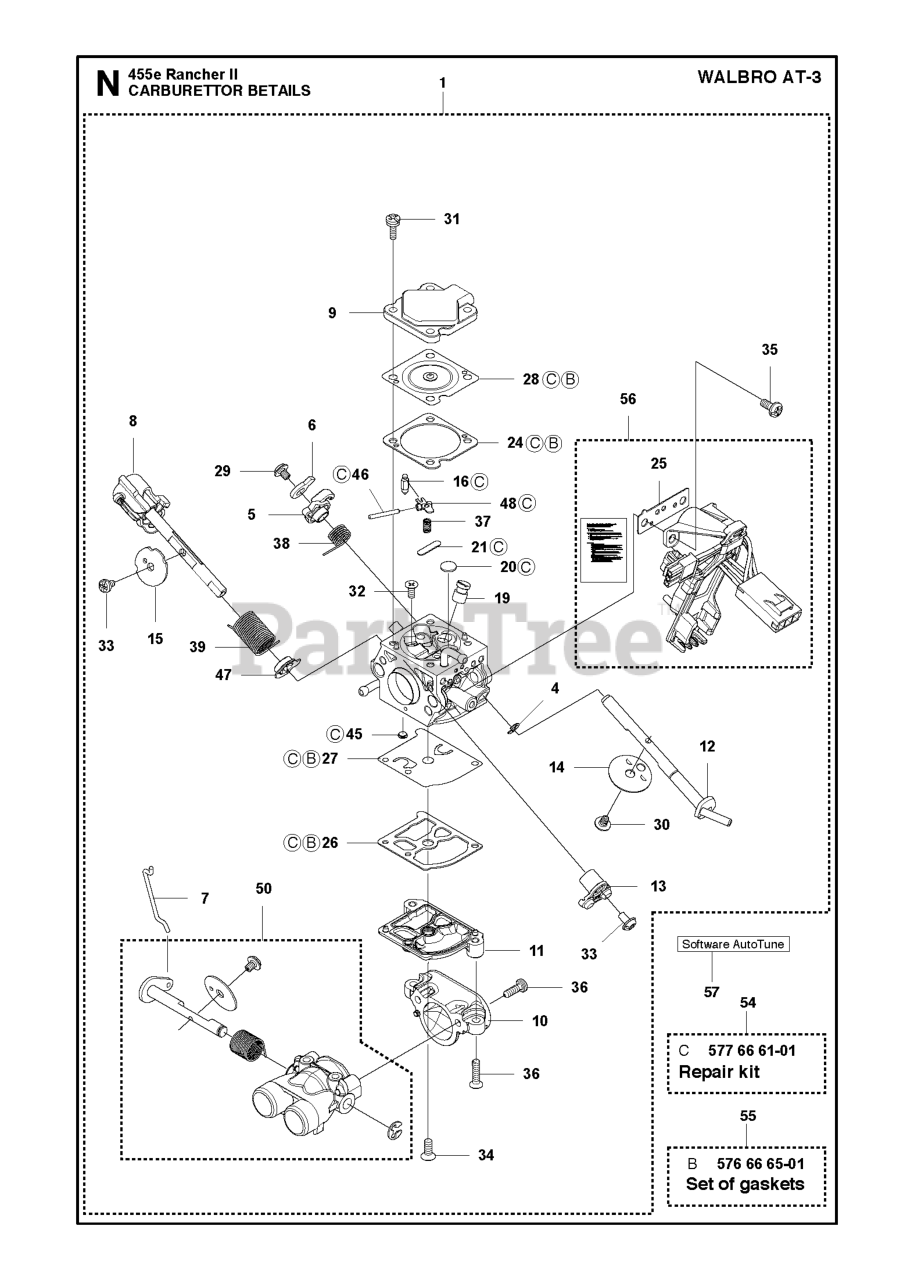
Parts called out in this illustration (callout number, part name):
1	CARBURETOR
4	RETAINER
5	LEVER
6	LEVER
7	LINK
8	THROTTLE LEVER
9	COVER
10	INLET
11	COVER
12	SHAFT ASSY
13	THROTTLE SHAFT
14	VALVE
15	THROTTLE VALVE
16	INLET NEEDLE
19	MAIN NOZZLE
20	PLUG WELCH
21	PLUG
24	GASKET
25	GASKET
26	GASKET
27	DIAPHRAGM
28	DIAPHRAGM ASSY
29	SCREW
30	SCREW
31	SCREW
32	SCREW
33	SCREW
34	SCREW
35	SCREW
36	SCREW
37	SPRING
38	SPRING
39	SPRING
45	FUEL INLET SCREEN
46	FULCRUM PIN
47	BUSHING
48	LEVER
50	THROTTLE VALVE ASSY
54	REPAIR KIT
55	GASKET KIT
56	SPARE PARTS KIT
57	Husqvarna TBD
